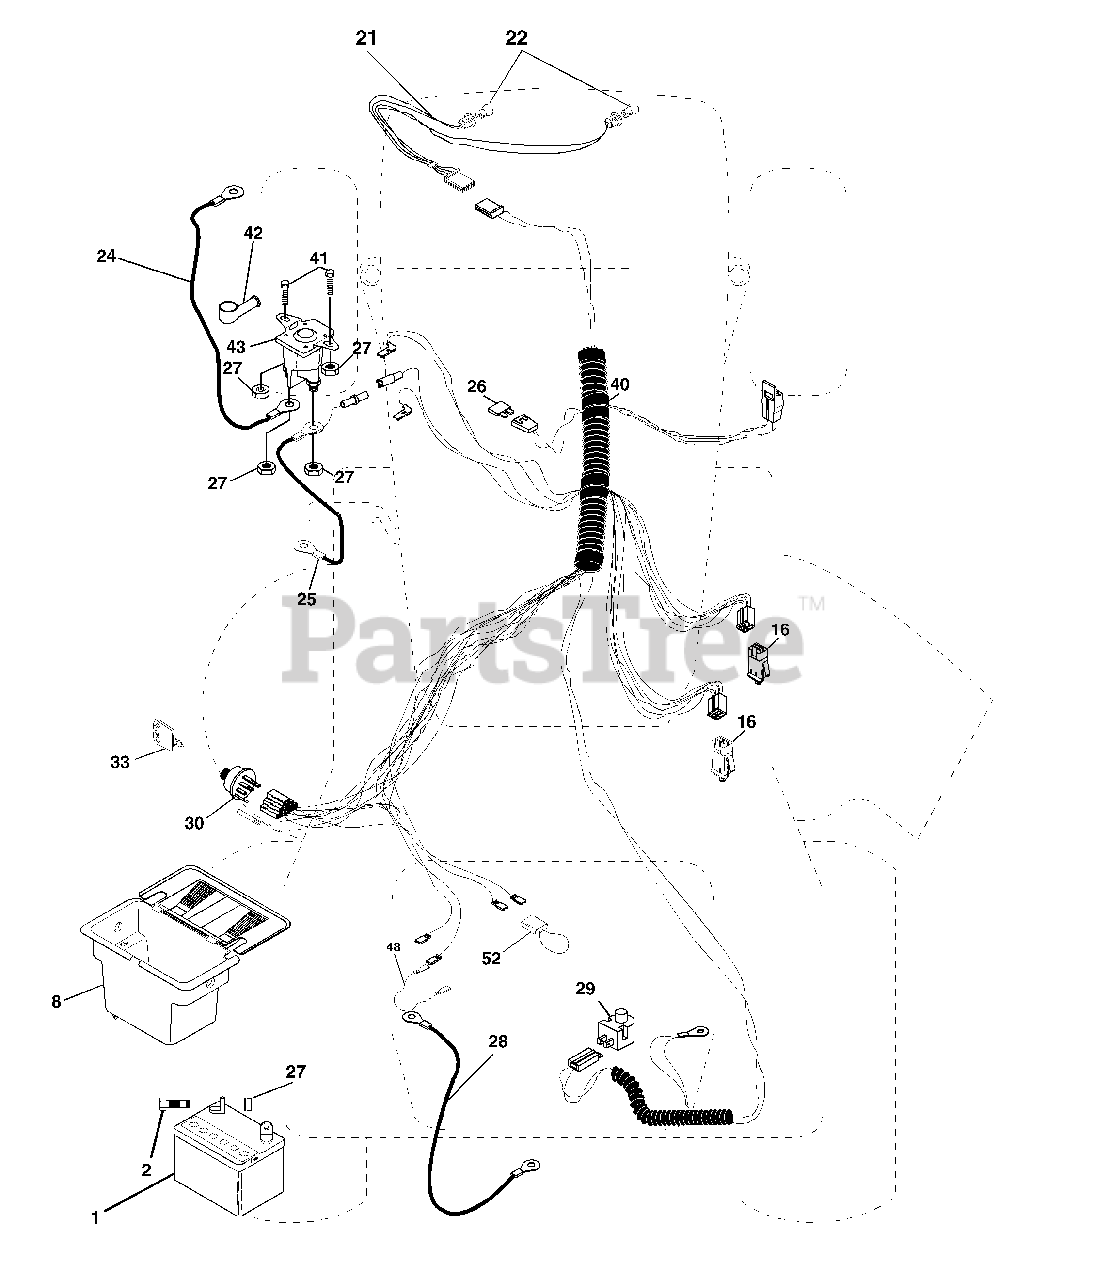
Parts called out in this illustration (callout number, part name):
1	Battery 12 Volt 25 Amp
2	Bolt Hex Hd 1/4-20unc X 3/4
8	Case Battery
16	Switch Interlock Push -In
21	Harness Asm Light W/4152J
22	Bulb Light #1156
24	Cable Battery 6 Ga 11"red
25	Cable Battery 6 Ga w/16 wire,red
26	Fuse 20 AMP
27	Nut Keps Hex 1/4-20 unc
28	Cable Ground 6 Ga 12" black
29	Switch Plunger Nc Gray
30	Switch Ign
33	Key Ign
40	Harness Ign
41	Bolt Blk Fin Hex 1/4-20 X 1/2
42	Cover Terminal Red
48	Adaptor Ammeter Rectangular
52	Protection Wire Loop
